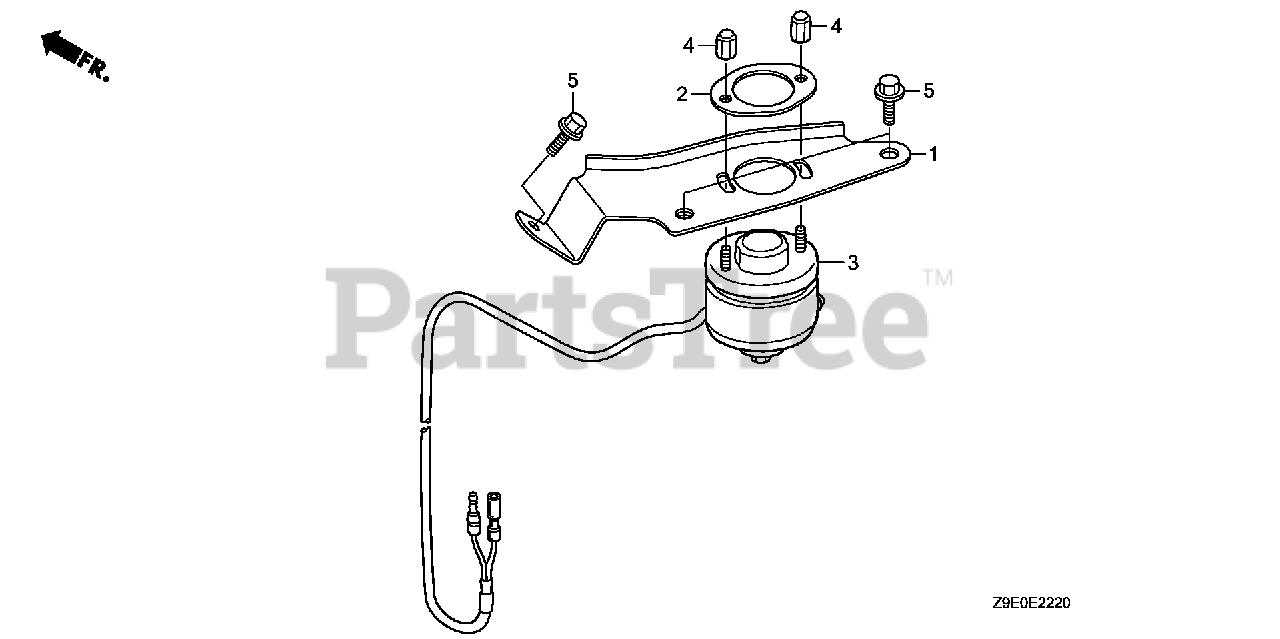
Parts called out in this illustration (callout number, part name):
1	STAY, SOLENOID
2	PLATE, SOLENOID
3	SOLENOID ASSY., ROTARY
4	NUT, SPECIAL CAP
5	BOLT, FLANGE (6X14)
